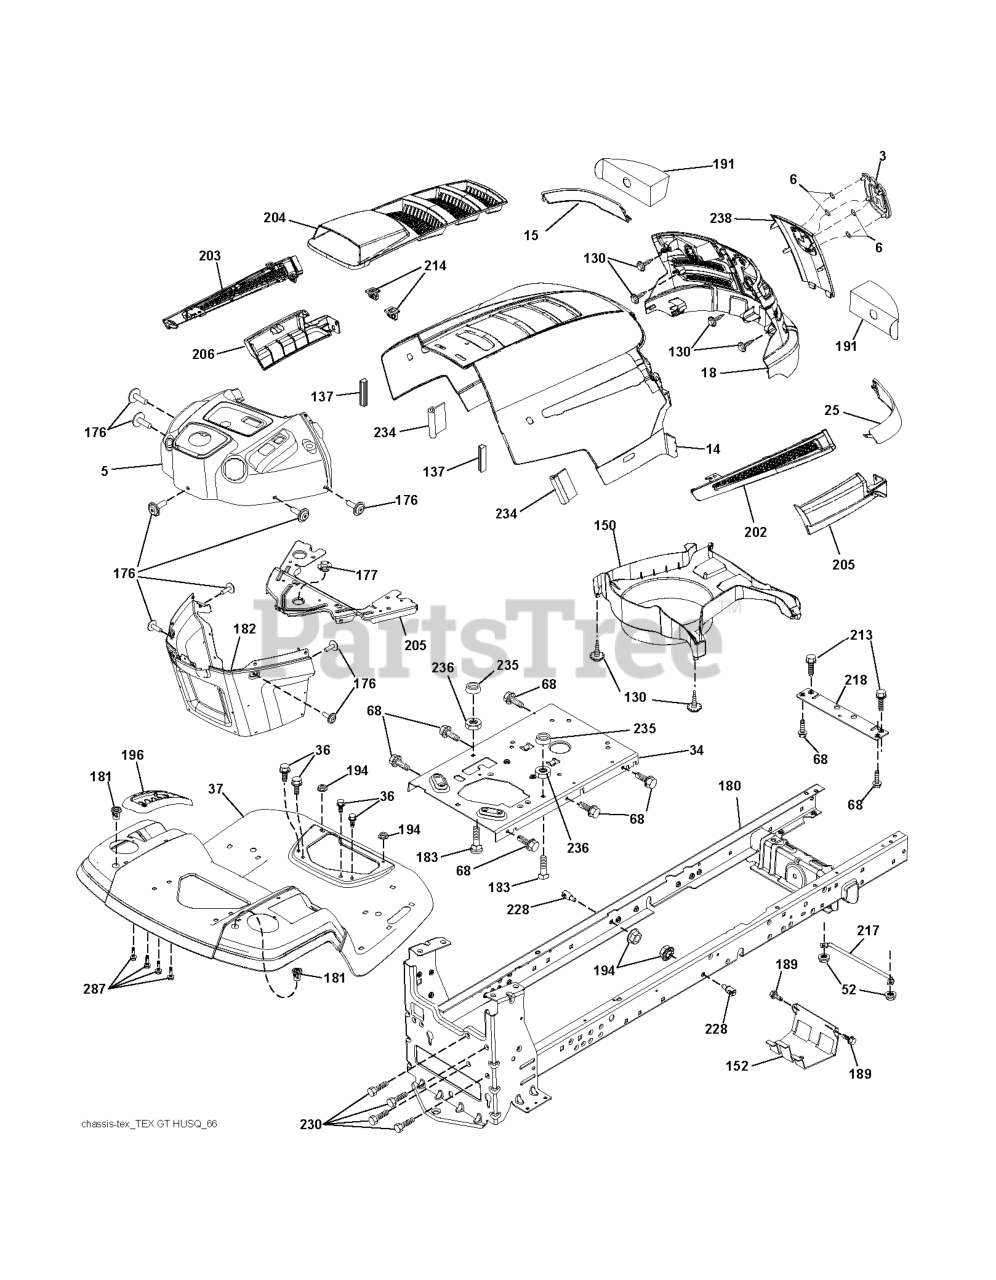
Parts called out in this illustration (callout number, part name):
3	RP LOGO
5	DASH
14	HOOD
15	LENS.HUSQVARNA LT.LH
18	RP GRILLE/LENS ASM.
25	LENS.HUSQVARNA LT.RH
34	PLATE.ENGINE.WELDED.CHASSIS
36	SCREW 3/8-16X3/4
52	LOCKNUT
68	Screw 5/16-18 x 1/2 Hex, Self Tapping 5/16-18 x 1/2
130	SCREW
137	BUMPER DASH
152	SHIELD.BROWNING.W/TEX
174	NUT PUSH M
175	CROSSMEMBER
176	SCREW.#10-24X5/8.RN.QU
177	BUSHING STEERING
180	CHASSIS
181	BUSHING.MNT.FEND.CRGO.
182	DASH LOWER
183	BOLT.5/16-18X1-1/4 FULL.THREAD
189	SCREW
191	INSERT REFLECTIVE
194	NUT LOCK HEX FLANGE 5/16-18
196	CONSOLE.ASM.DECK.LIFT.
202	VENT SIDE HOOD RH
203	VENT SIDE HOOD LH
204	VENT TOP HOOD
205	SKIRT SIDE RH
206	SKIRT SIDE LH
213	BOLT
214	CLIP.RETAINER.TINNER.
217	ROD PIVOT CHASSIS/HOOD
218	X-PIECE.HOOD.STOP.NON/
222	SCREW.1/4-20X5/8
228	STUD.FASTNER.W/ANTI-ROTATE
230	SHOULDER BOLT 5/16-18TT
234	BUMPER.HOOD.TEX.HUSQVARNA
235	SPACER FENDER
236	NUT.CENTERLOCK.5/16-
238	TRIM
